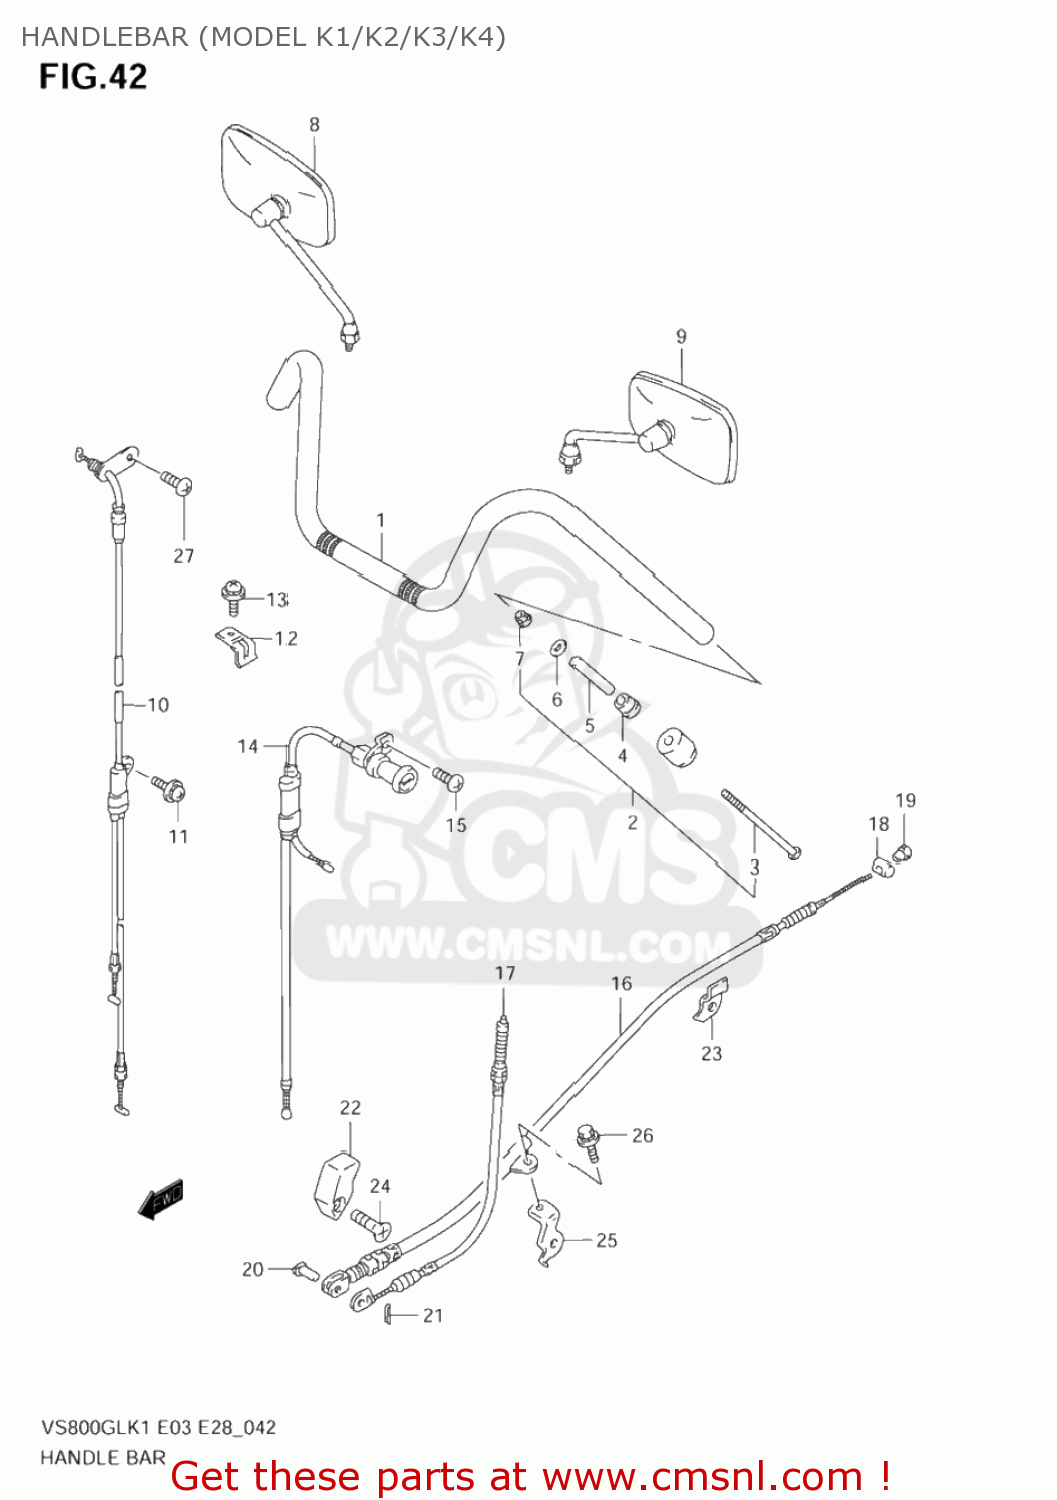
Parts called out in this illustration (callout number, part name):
1	HANDLEBAR
2	BALANCER SET,HANDLEBAR
3	SCREW(6X110)
4	EXPANDER,HANDLE BALANCER NO.2
5	SPACER,EXPANDER
6	WASHER(6.5X18X2)
7	NUT
8	MIRROR ASSY,RR VIEW,R
9	MIRROR ASSY,RR VIEW,L
10	CABLE ASSY,THROTTLE
11	SCREW
12	CLAMP,THROTTLE CABLE
13	SCREW
14	CABLE ASSY,STARTER
15	SCREW 6X10
16	CABLE,RR BRAKE
17	CABLE,STOP LAMP SWITCH
18	PIN(13X18)
19	NUT
20	PIN(L:17.5)
21	PIN
22	GUIDE,RR BRAKE CABLE
23	CLAMP,RR BRAKE CABLE
24	SCREW
25	BRACKET,RR BRAKE CABLE
26	BOLT
27	SCREW
